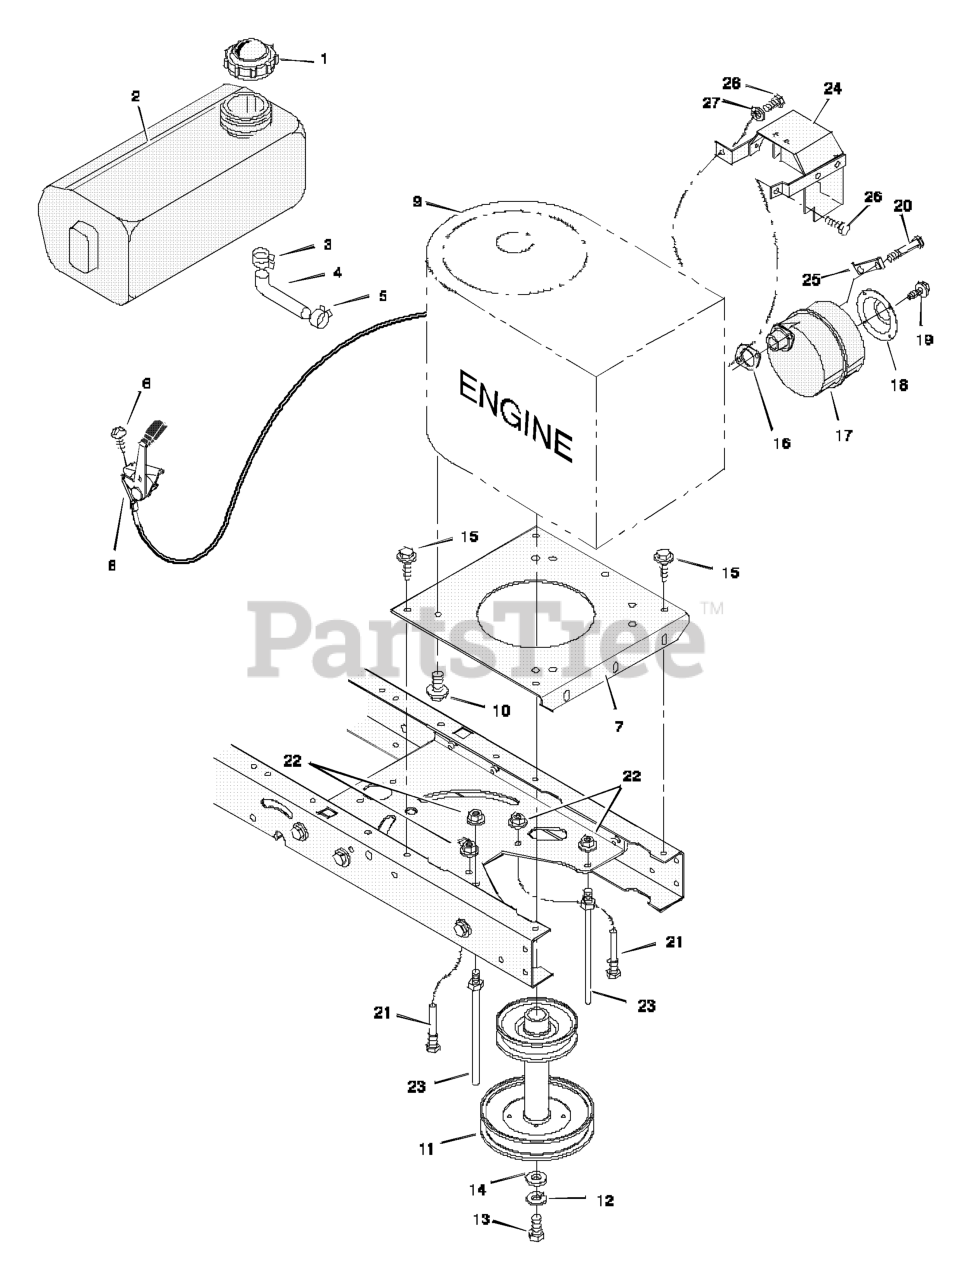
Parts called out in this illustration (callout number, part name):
1	Fuel Cap
2	Fuel Tank
3	Hose Clamp
4	Fuel Line
5	Hose Clamp
7	Plate, Engine
8	Throttle Control
9	Engine *
10	Bolt, Engine Mount
11	Stack Pulley Assembly
12	Lockwasher
13	Bolt, Hex
16	GASKET, Exhaust
17	Muffler
18	Deflector, Muffler
20	Bolt, Hex
21	Guide, Belt
22	Nut, Flange
23	Guide, Belt
24	Shield, Heat
25	Lock, Screw
